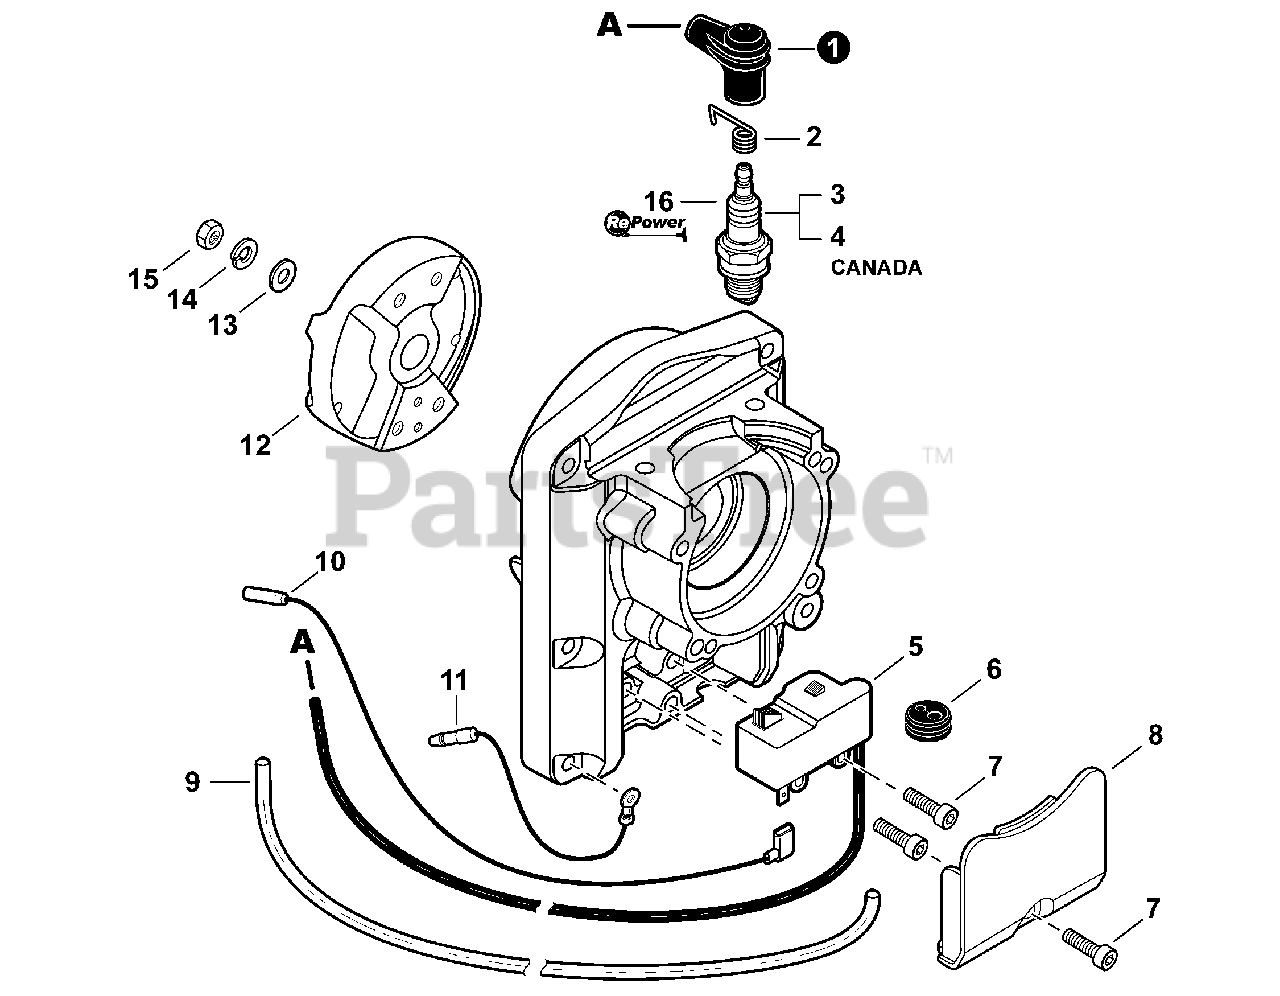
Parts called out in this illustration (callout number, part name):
1	CAP, SPARK PLUG
2	TERMINAL, SPARK PLUG
3	SPARK PLUG - BPM-8Y
4	SPARK PLUG - BPMR-8Y
5	COIL, IGNITION
7	BOLT, TORX 5×16
8	COVER, DUST
10	LEAD - IGNITION
11	LEAD - GROUND
12	FLYWHEEL
13	WASHER 10
14	WASHER, SPRING 10
16	TUNE-UP KIT - REPOWER
